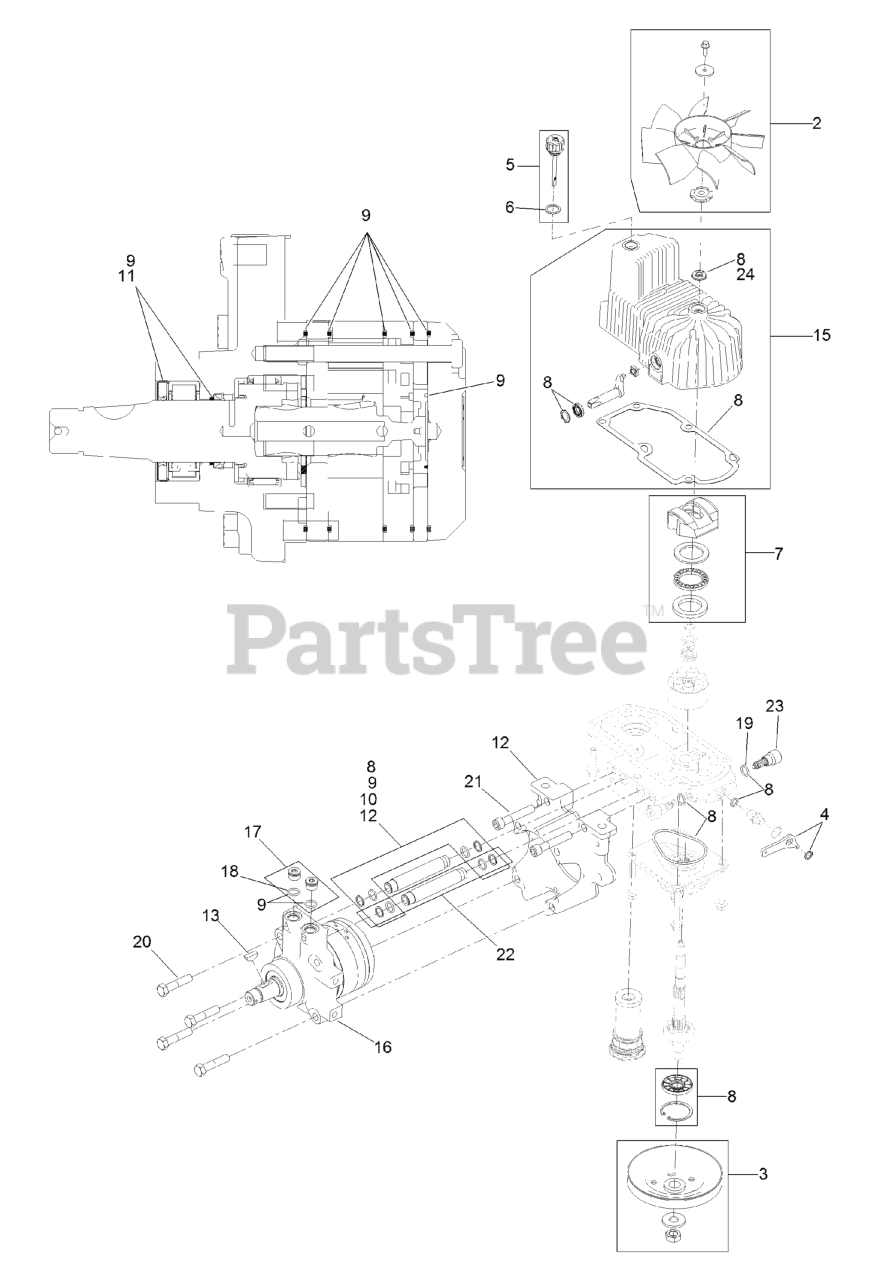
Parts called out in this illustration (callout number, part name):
2	FAN KIT
3	PULLEY KIT
4	HANDLE-BYPASS VALVE, HYDRO
5	DIPSTICK-HYDRO W/GASKET
6	GASKET-DIPSTICK, HYDRO
7	SWASH BLOCK KIT
8	PUMP SEAL KIT
9	MOTOR SEAL KIT
10	TUBE SEAL KIT
11	OUTPUT SHAFT SEAL KIT
12	NOSE CUP-UHT
13	KEY-WOODRUFF
15	HOUSING-HYDRO, LH
16	MOTOR-HYDRAULIC, LH 280CC
17	MAGNETIC PLUGS SERVICE KIT
19	O-RING-CHECK VALVE
20	SCREW HH
21	SCREW-HSH
22	HYDRAULIC TUBE KIT
23	SHOCK VALVE, 16CC HYDRO
24	SEAL-FAN DRIVE
25	16Cc LH Pump Section Kit
26	16Cc LH Rotating Grp Kit
99	PULLER-PULLEY
